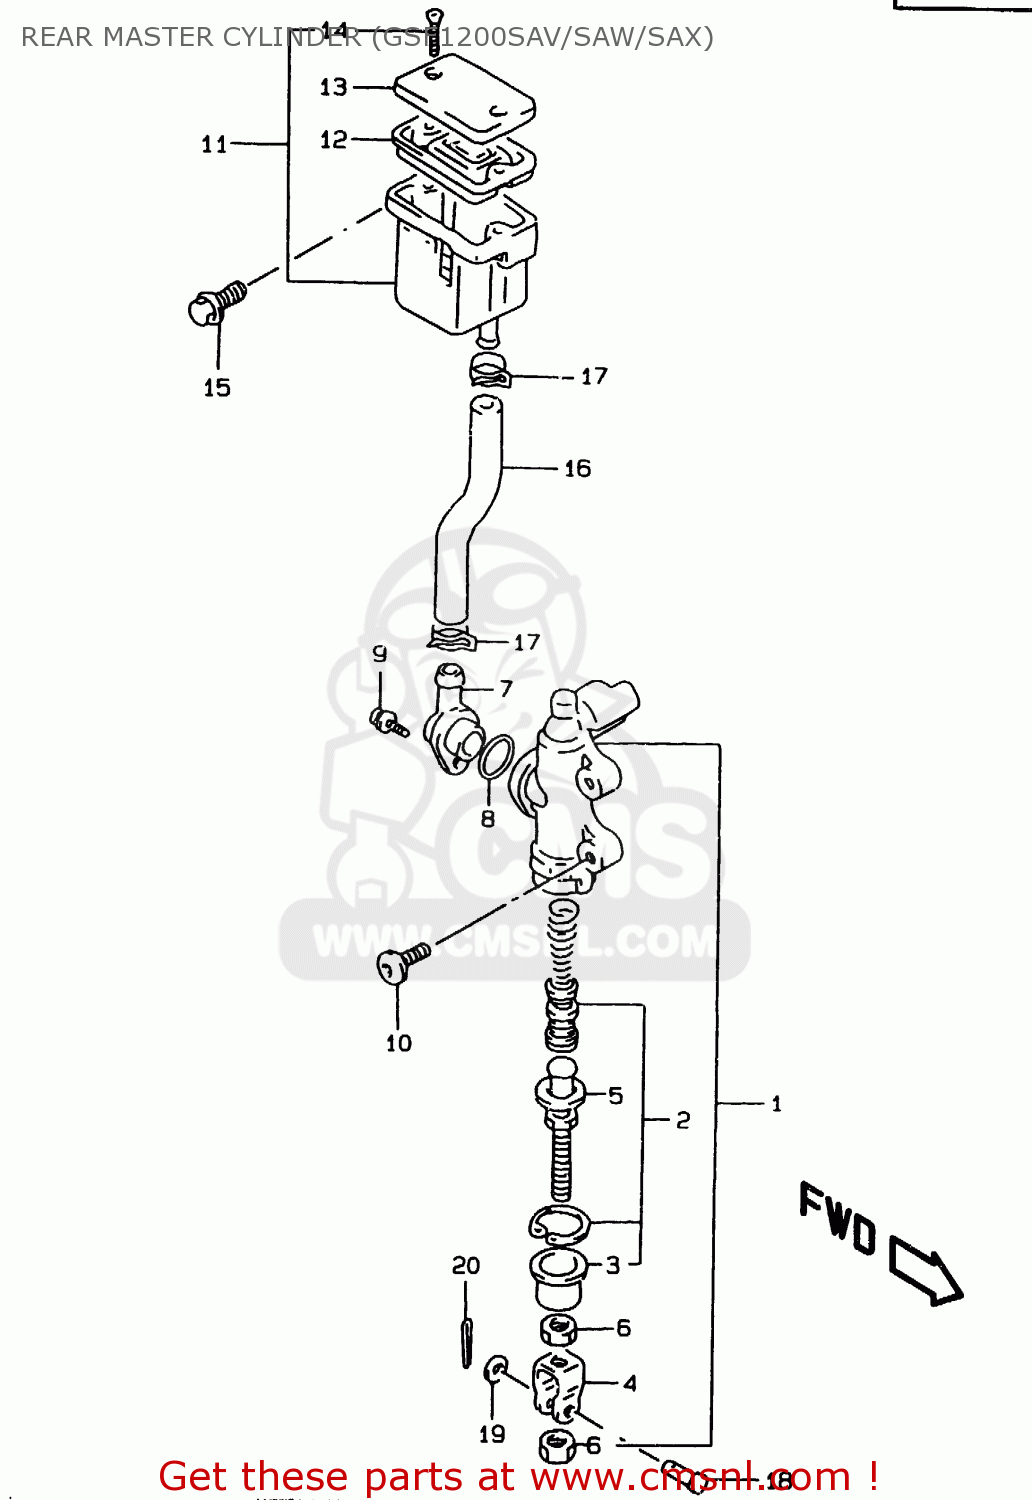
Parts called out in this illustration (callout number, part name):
1	CYLINDER ASSY,RR MASTER
2	PISTON/CUP SET
3	BOOT
4	YOKE
5	ROD,PUSH
6	NUT
7	CONNECTOR
8	O RING
9	SCREW
10	BOLT 8X20
11	TANK ASSY,RESERVOIR
12	DIAPHRAGM
13	CAP
14	SCREW
15	BOLT
16	HOSE,RESERVOIR TANK
17	CLIP
18	PIN
19	WASHER
20	PIN
